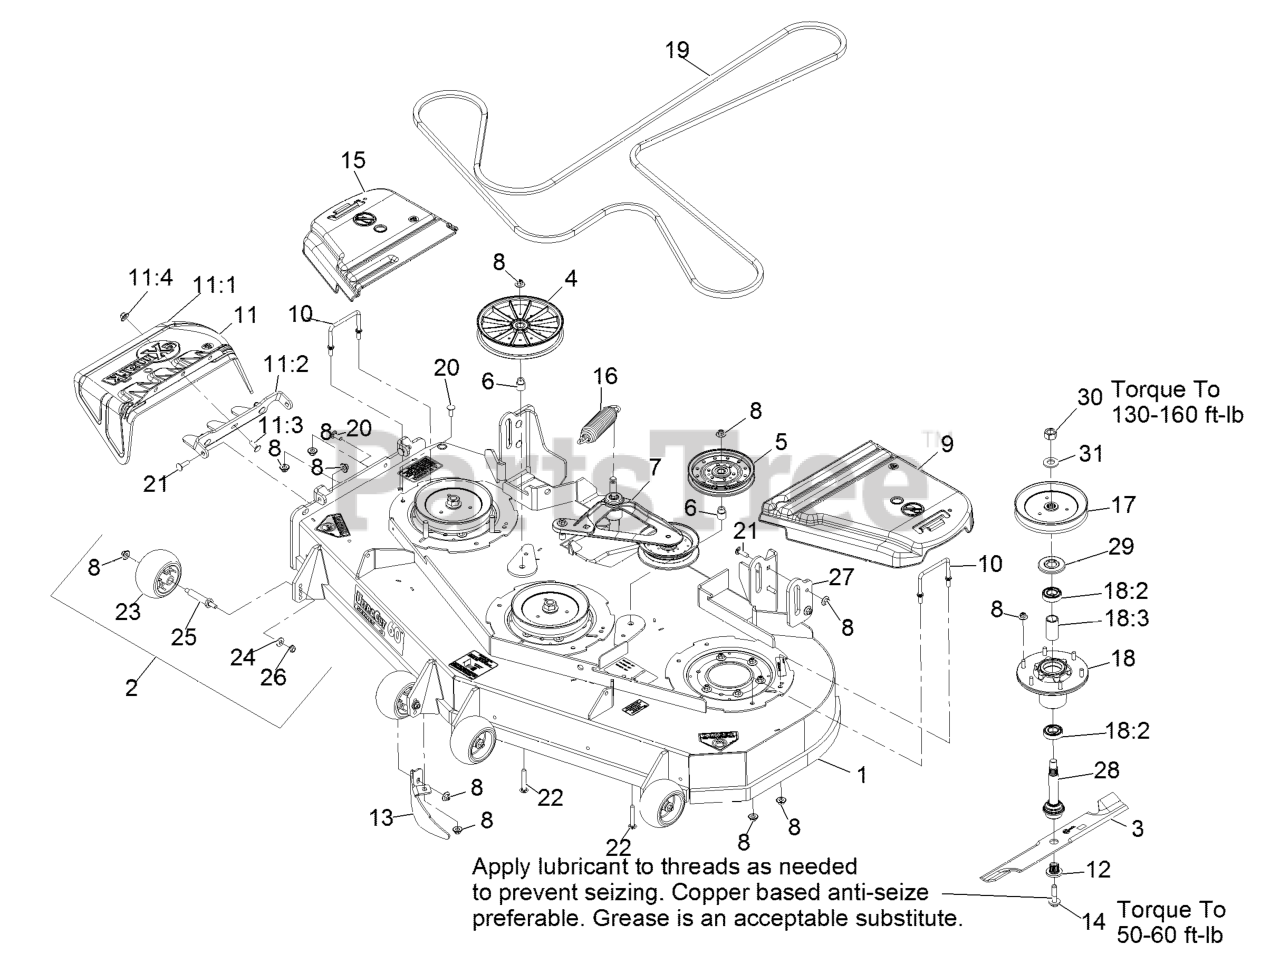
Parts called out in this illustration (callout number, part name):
1	DECK ASM, W/DECALS 604
3	Blade-Extreme 2, 20.50"
4	PULLEY,IDLER 8"FLAT
6	BUSHING-IDLER
7	DECK IDLER ASM
8	Nut-Nyloc 3/8-16 Flg
9	COVER-BELT, LH
10	WIREFORM-COVER
11	ASM,DISCHARGE CHUTE
11:1	CHUTE,DISCHARGE
11:2	BRACKET,DISCHARGE CHUTE
11:3	SCREW-CARR
11:4	Nut-Nyloc 3/8-16 Flg
12	BUSHING,SPLINED
13	DOGLEG - LZ60
14	SCREW,SEMS 1/2-20 X 2.19
15	COVER-BELT, RH
16	SPRING-EXTENSION
17	SHEAVE,BLADE DRIVE 7.25
18	ASM-CUTTER HSG WITH BEARINGS
18:2	BEARING-BALL
18:3	SPACER-BEARING
19	BELT,V-5V-198.75
20	SCREW-CARR
21	Bolt-Carriage 3/8-16 X 1 1/4
22	SCREW-CARR
23	ROLLER-SCALP, ANTI
24	WASHER-BELLEVILLE
26	NUT-HHF, WHIZ
27	PLATE-REINF, PUSH TOWER
28	ASM-SPINDLE AND SEAL
29	GUARD,BEARING TOP .989
30	NUT-HEX
